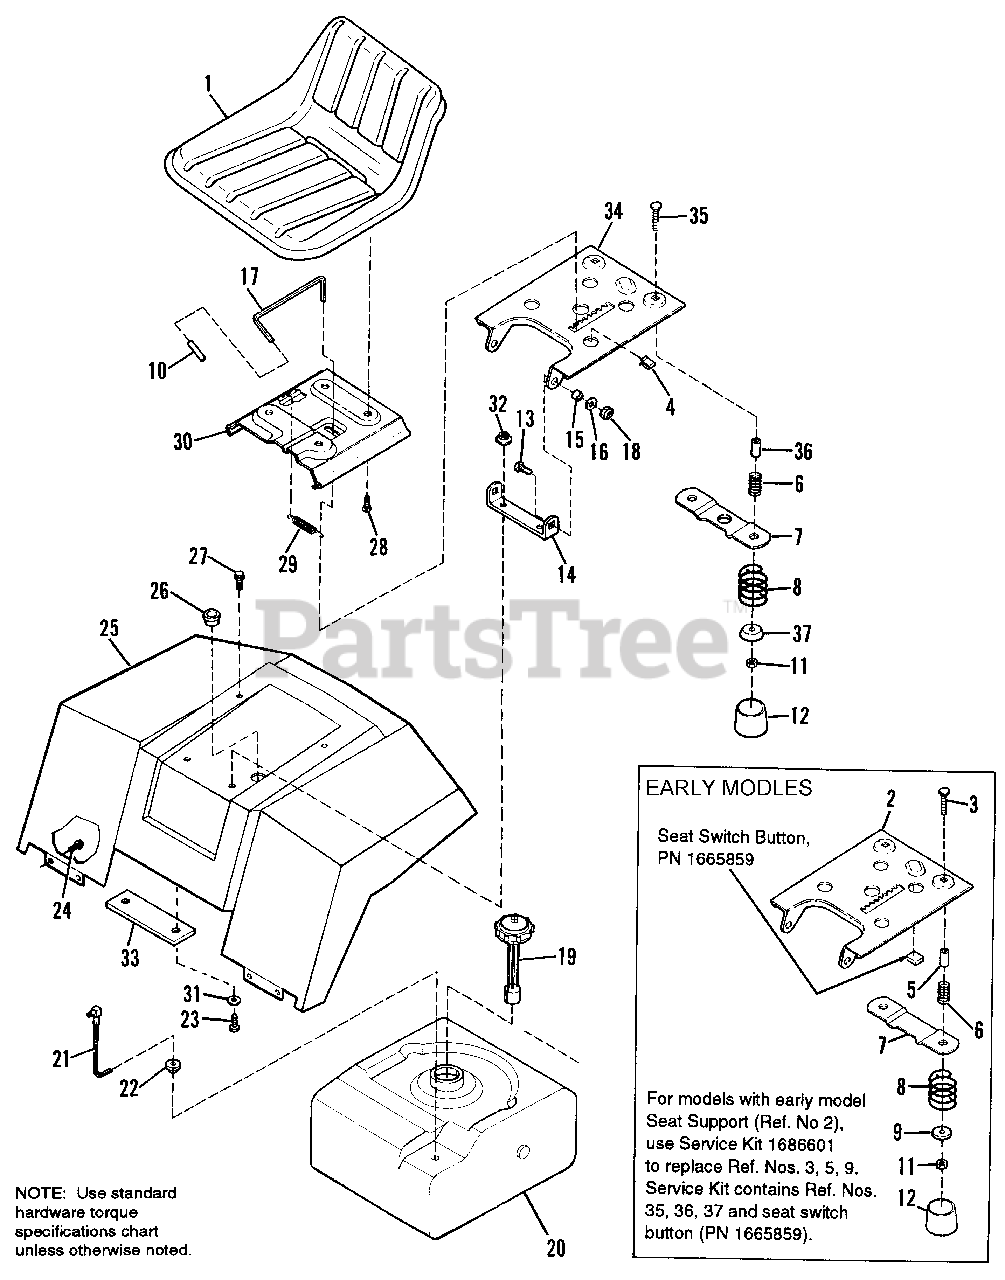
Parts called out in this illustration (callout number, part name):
2	SUPPORT, Seat, Pivot (Early models - see note on illustration page)
3	CARRIAGE BOLT, 5/16-18 x 1-3/4 (Early models)
4	CLIP, Speed
5	SPACER (Early models)
6	SPRING, Compression
7	PLATE, Switch
8	SPRING, Compression, 2" O.D.
9	WASHER, Plain (Early models)
10	HANDLE, Grip
11	NUT, Hex, Full, 5/16-18
12	COVER, Spring
13	CARRIAGE BOLT, 3/8-16 x 1
14	BRACKET, Seat, Pivot
16	WASHER, Plain, 13/32
17	LEVER, Seat Release
18	NUT, Hex Hd., Nyloc, 3/8-16
19	CAP, Fuel Gauge
20	TANK, Fuel
21	ELBOW & TUBE ASSY.
23	SCREW, Truss Hd., Torx Dr., 3/8-16 x 1
24	SCREW, Taptite, 1/4-20 x 1/2
25	SEAT DECK (Orange)
25	SEAT DECK (Green)
25	SEAT DECK (Red)
26	BUSHING, Snap
27	SCREW, Taptite, 5/16-18 x 5/8
28	BOLT, Hex, Whizlock, 5/16-18 x 5/8
30	BRACKET, Seat Slide
31	WASHER, Plain, 1-1/2 O.D. (Early models only)
32	NUT, Hex, Flange, Whizlock, 3/8-16
33	PLATE, Reinforcement (Later models only)
34	SUPPORT, Seat, Pivot (Later models only)
35	CARRIAGE BOLT, 5/16-18 x 2 (Later models only)
36	SPACER (Later models only)
37	WASHER, Plain (Later models only)
